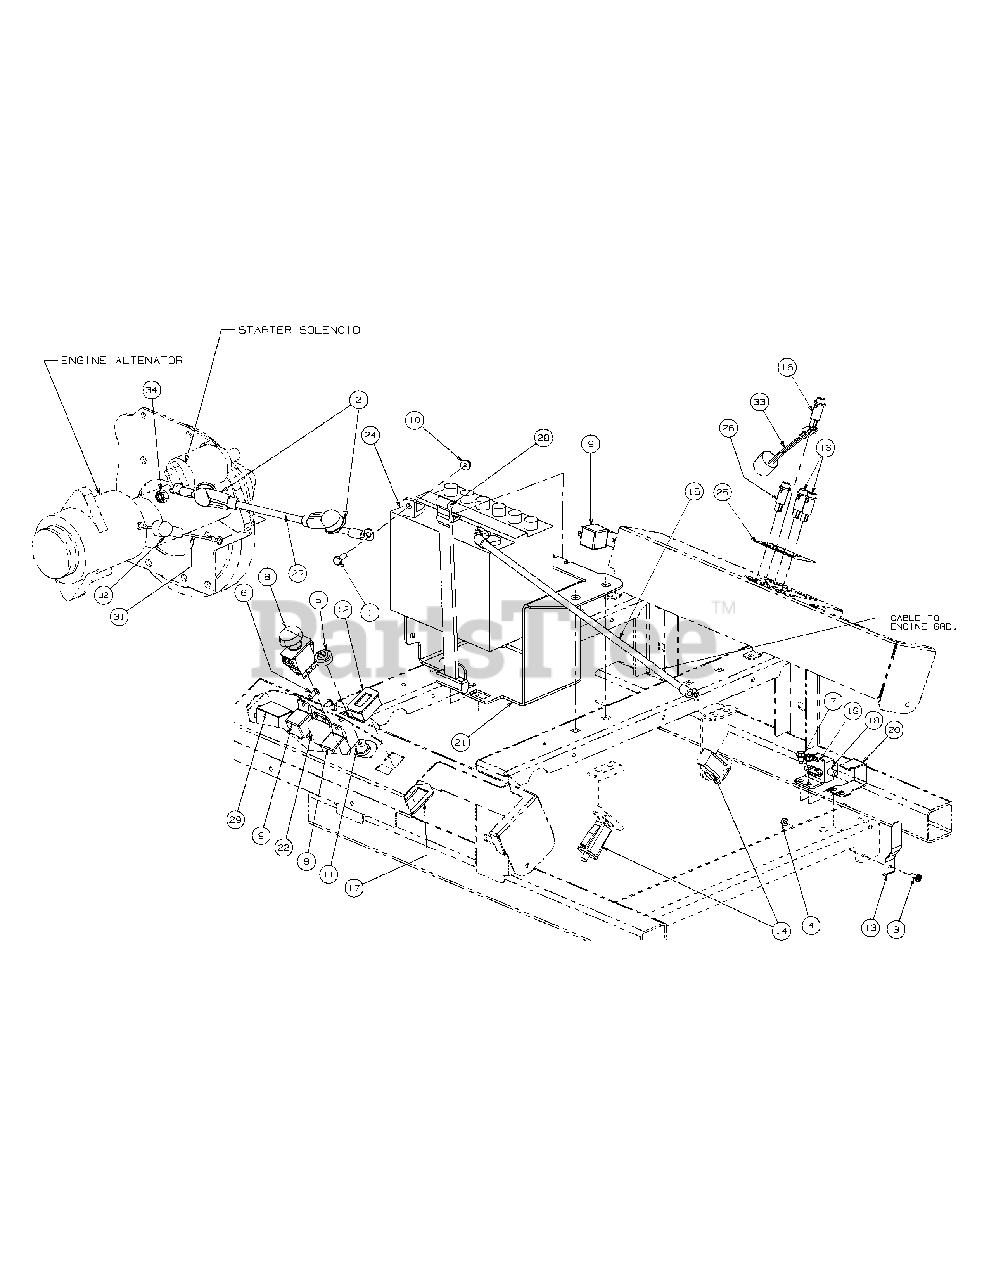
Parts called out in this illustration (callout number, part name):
1	Screw, Hex, Cap, 1/4-20 x .75
2	Boot, 1" OD Rubber Battery-PST, Red
3	Screw, Hex Washer, 10-32 x 1/2
4	Lock Nut, Nylon Insert
5	Nut, W/Cap, 5/8-32 Ignition
6	Screw Button Head, 1/4-20 x .5
7	Screw, TT, 1/4-20, 0.5, Hex Index Washer
8	Switch, Electric, PTO
9	Relay, 12V 40A
10	Lock Nut, 1/4-20
11	Switch, Ignition, 6 Pin
12	Meter, Hour
13	Spring Retainer
14	Switch, Plunger
15	Cable, Battery Black, 34"
16	Light Indicator, 12V
17	Bracket, PTO Switch Retainer
18	Switch, Plunger
19	Bracket, Plunger Switch
20	Clamp, Plunger Switch
21	Mount Bracket, Battery
22	Interlock Time Delay Shutdown
24	Battery, 320CCA
25	Decal, Engine Light
26	Light Indicator, 12V
27	Cable, Battery Red, 42"
28	Strap, Battery
29	Timer Relay
30	Tie, Cable, 3/16 x .05 x 7.4"
31	Wire, Alternator Charge
32	Cover, Alternator
33	Alarm, High Temperature
34	Nut, Hex, Center Lock, M8
